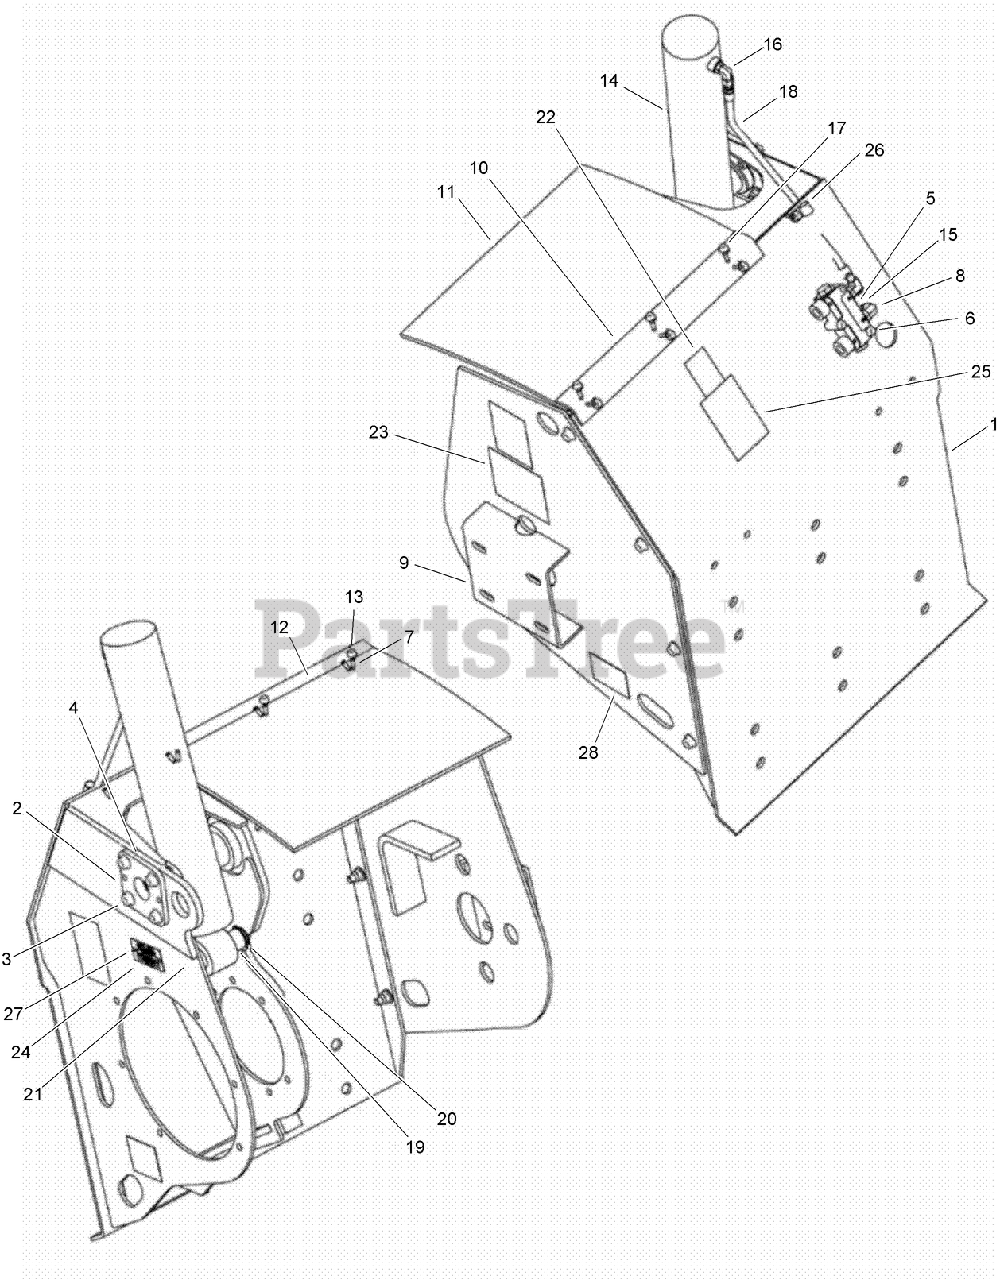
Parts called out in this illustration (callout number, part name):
1	WELDMENT-Trencher Frame
2	PIVOT BLOCK ASM
4	NUT-HHF, LOCK
5	HYD LOCKOUT VALVE ASM
6	SCREW-FLANGE
7	NUT-TORQUE, PREVAILING
8	ELBOW-90 Adj 37FL, 3/8 x 1/2 Tube
9	WELDMENT-Bearing Support Plate
10	ANGLE-Dirt Deflector
11	DEFLECTOR-DIRT
12	STRIP-Dirt Deflector
13	SCREW, METRIC FLANGE FULL - M8 x 25
14	CYLINDER-BOOM LIFT
15	HOSE-Hydraulic
16	ELBOW-90 DEG (ADJUSTABLE 37 DEG)
17	CONNECTOR-Str Thd 3/8, 37FL-ORB 3/8
18	HOSE-Hydraulic
19	PIN-PIVOT
21	FITTING-Lube 1/8-27 Dryseal PTF
22	DECAL-Warning, Call Before Digging
23	DECAL-Planetary Oil / Lube Lever
24	PLATE - Serial Number
25	DECAL-Danger, Trencher Entanglement Hazard
27	TACK-FASTENER, STEEL
28	DECAL-Tie Down
